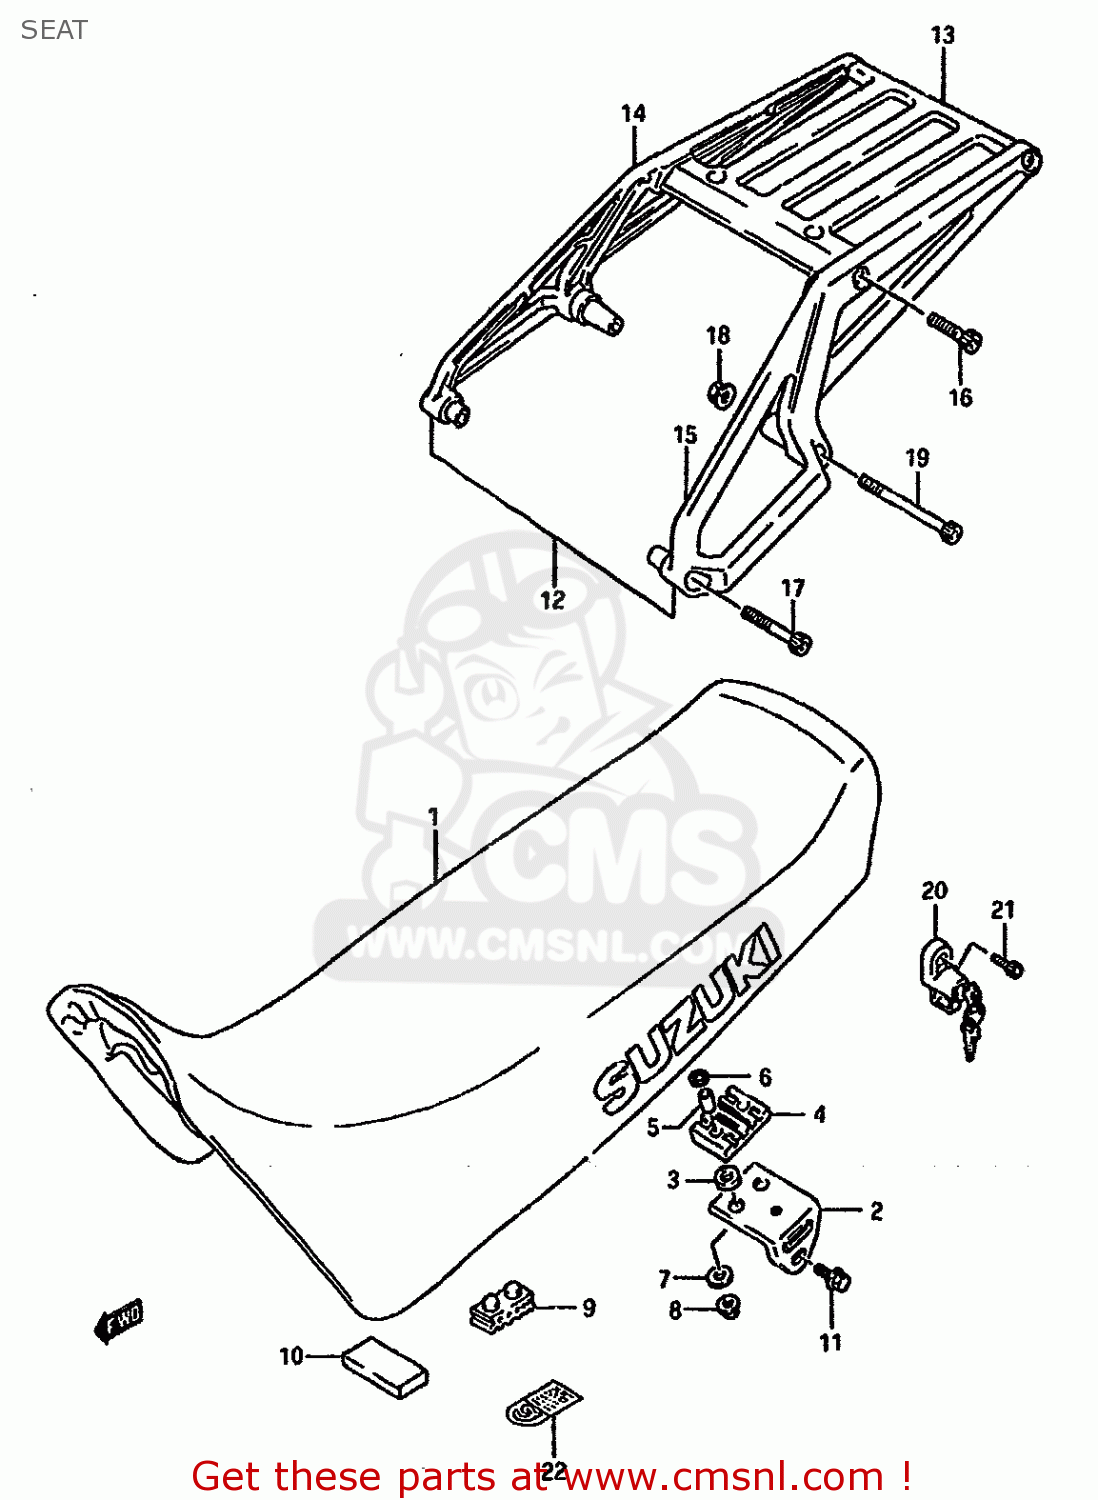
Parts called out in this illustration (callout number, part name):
1	SEAT SET
2	BRACKET,SEAT
3	CUSHION,SEAT FR
4	CUSHION,FR PLATE
5	SPACER,SEAT SUPPORT
6	WASHER
7	WASHER, LOWER
8	NUT
9	CUSHION,SEAT(40X20X15)
10	CUSHION(30X60X10)
11	BOLT
12	CARRIER,REAR (SILVER)
13	REAR CARRIER,CENTER (SILVER)
14	RR CARRIER R
15	REAR CARRIER,LH (SILVER)
16	BOLT
17	BOLT ,8X50
18	NUT
19	BOLT
20	LOCK SET,HELMET
21	BOLT
22	LABEL,ASBESTOS WARNING
